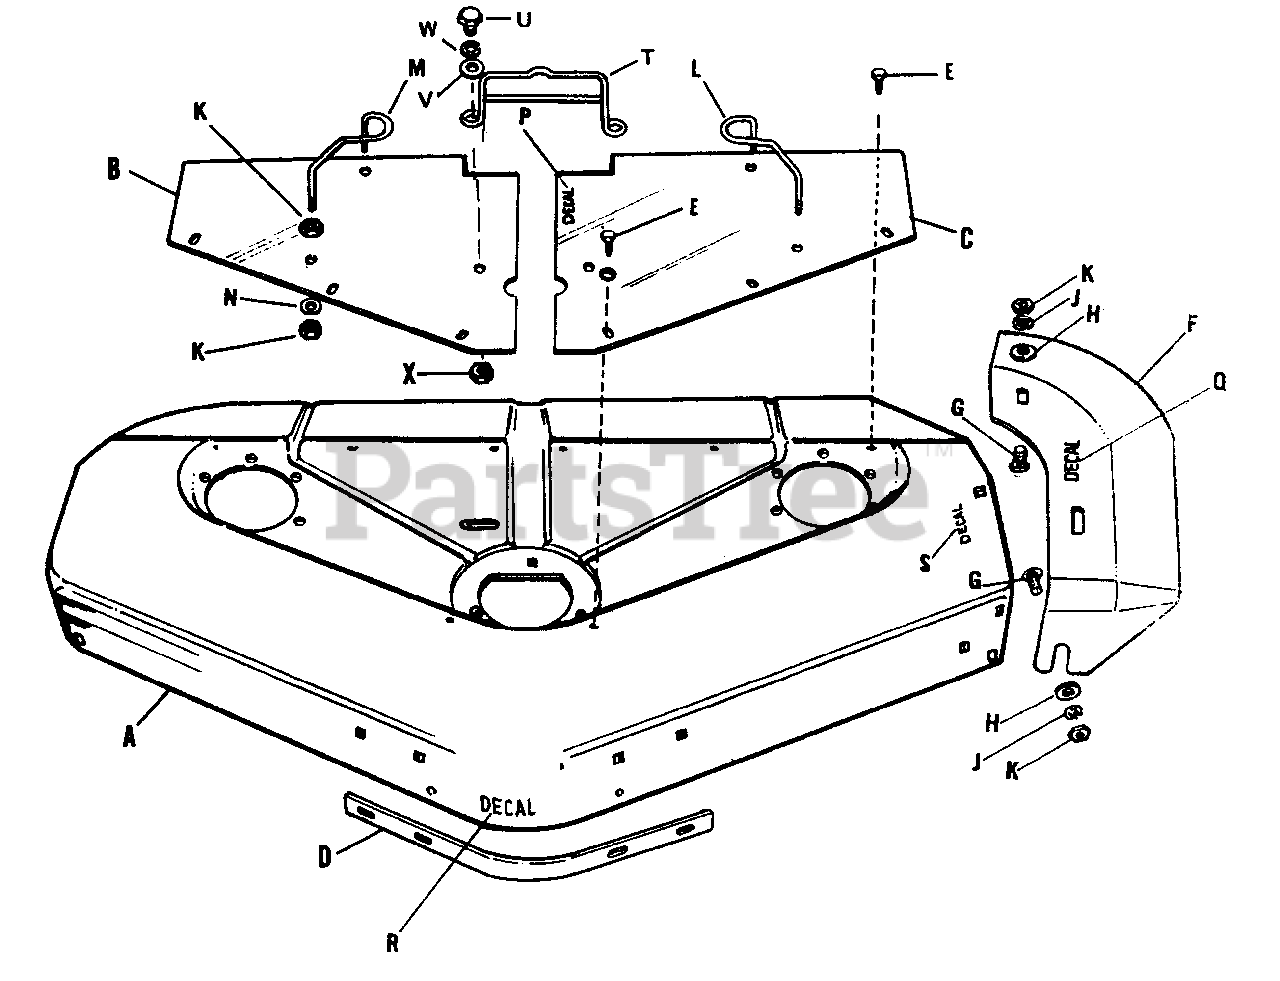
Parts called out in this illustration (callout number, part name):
A	Mower Housing
B	Cover, R.H.
C	Cover, L.H.
D	Bar, Reinforcing
E	Screw, Taptite, 1/4-20 x 3/8" lg.
F	Deflector
G	Carriage Bolt, 3/8"-16 x 3/4" lg.
H	Washer-Special
J	Washer, Lock, 3/8"
K	Hex Nut, Full, 3/8-16
L	Guard, L.H.
M	Guard, R.H.
N	Washer, Plain, 3/8
S	Film, Safety
T	Belt Guide Assembly
U	Hex Cap Screw, 5/16-18 x 3/4 lg.
V	Plain Washer 5/16
W	Lock Washer, 5/16
X	Nut Retainer
